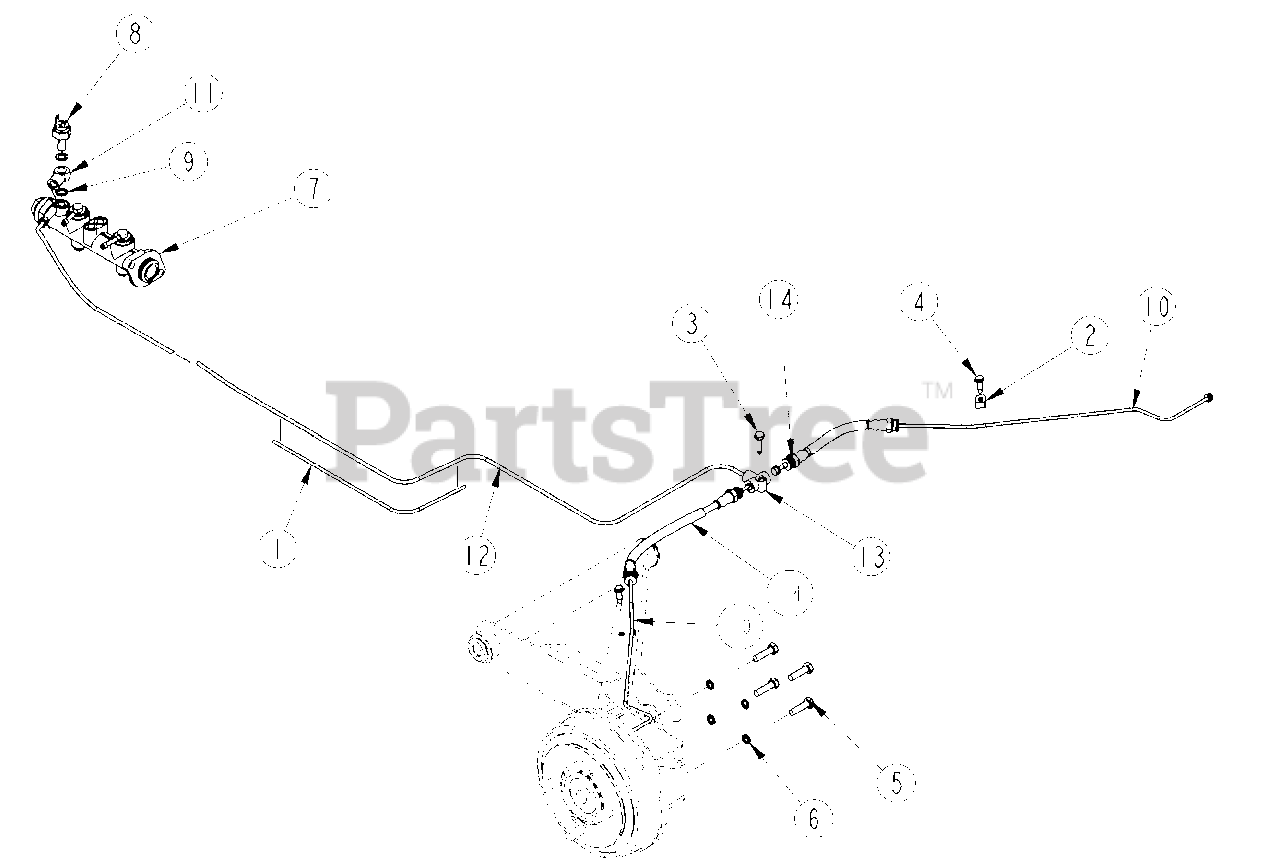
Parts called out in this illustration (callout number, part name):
1	COVER, BRAKE LINE 13.5"
2	WIRING/TUBE CLIP FOR 1/4 OD
3	SCR HEX SELF TAP 1/4-20X1TYPEF
4	HH DRILL SCREW 1/4 X 3/4LG
5	HHCS M8X1.25X30 GR10.9 ZNYCR
6	WASHER SPRING LOCK M8 PLT
7	DUAL MASTER CYLINDER
8	MASTER CYLINDER PRESS. SWITCH
9	MSTR CYL CPPR WSHR 16X10X1.5MM
10	REAR BRAKE LINE 28.3
11	BULK HEAD FLOW THROUGH
12	ST STEEL BRAKE LINE
13	FITTING 3 WAY HYD.
14	REAR RUBBER BRAKE LINE
